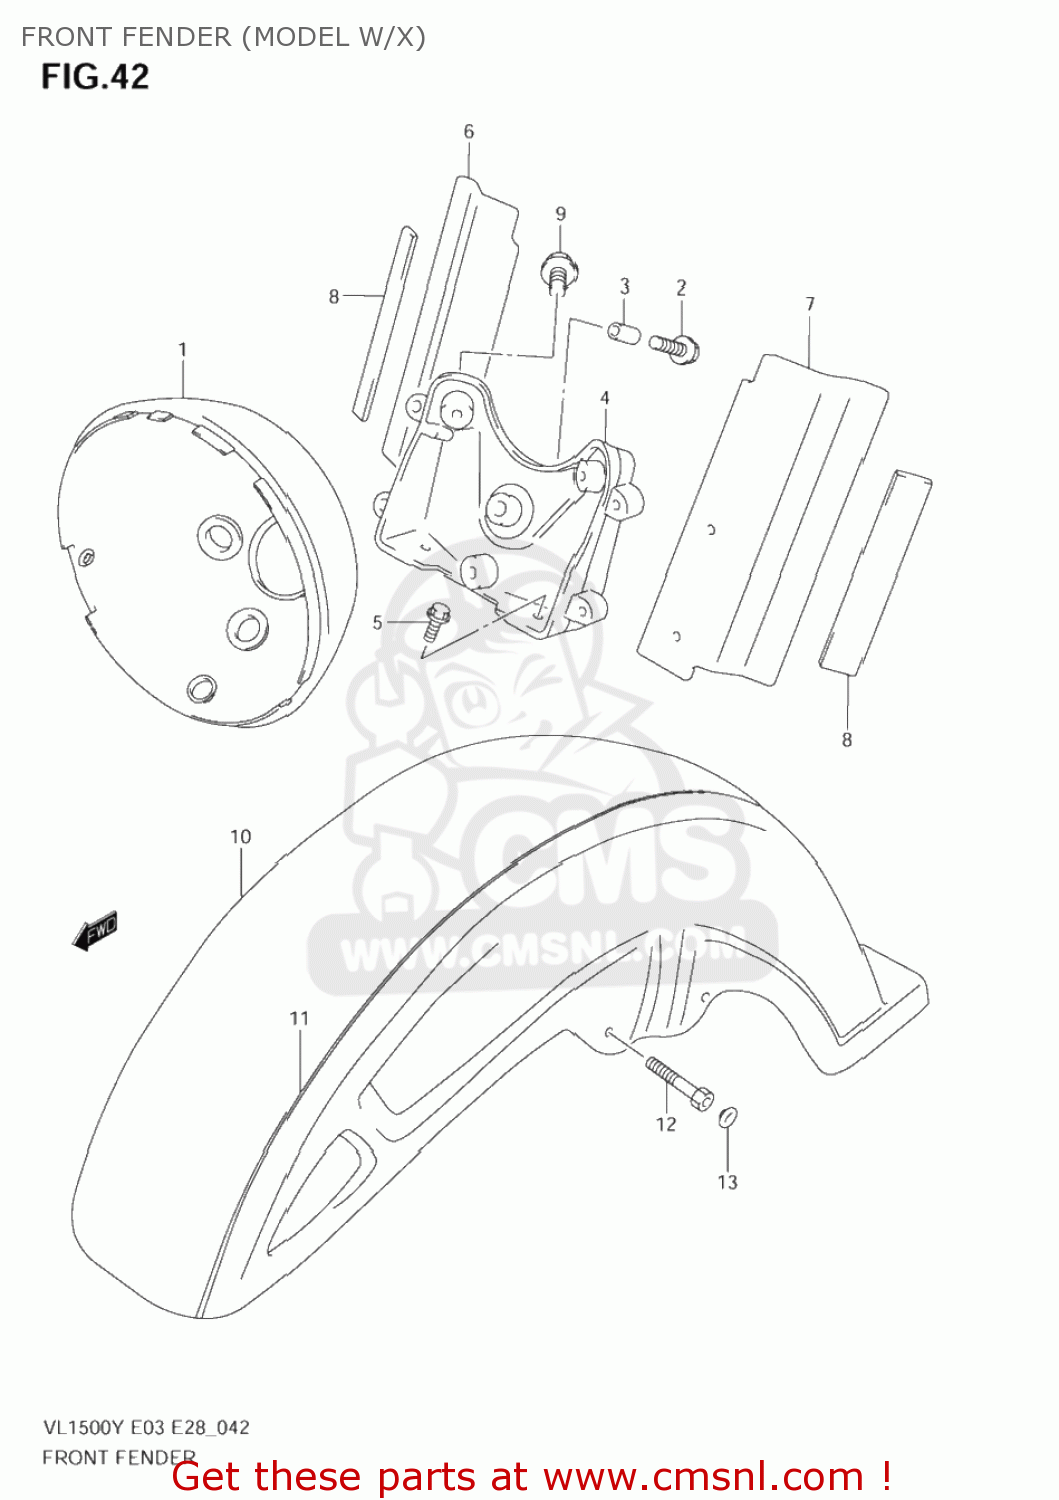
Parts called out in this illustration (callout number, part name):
1	HOUSING,HEADLAMP
2	BOLT(6X25)
3	SPACER(6.8X12X11)
4	BRACKET,HEADLAMP HOUSING
5	BOLT
6	PLATE,HEADLAMP BRACKET,R
7	PLATE,HEADLAMP BRACKET,L
8	PROTECTOR(170X95X3.0)
9	SCREW(6X12)
10	FENDER,FRONT
11	TAPE SET,FR FENDER
12	BOLT
13	CAP(OD:11)
